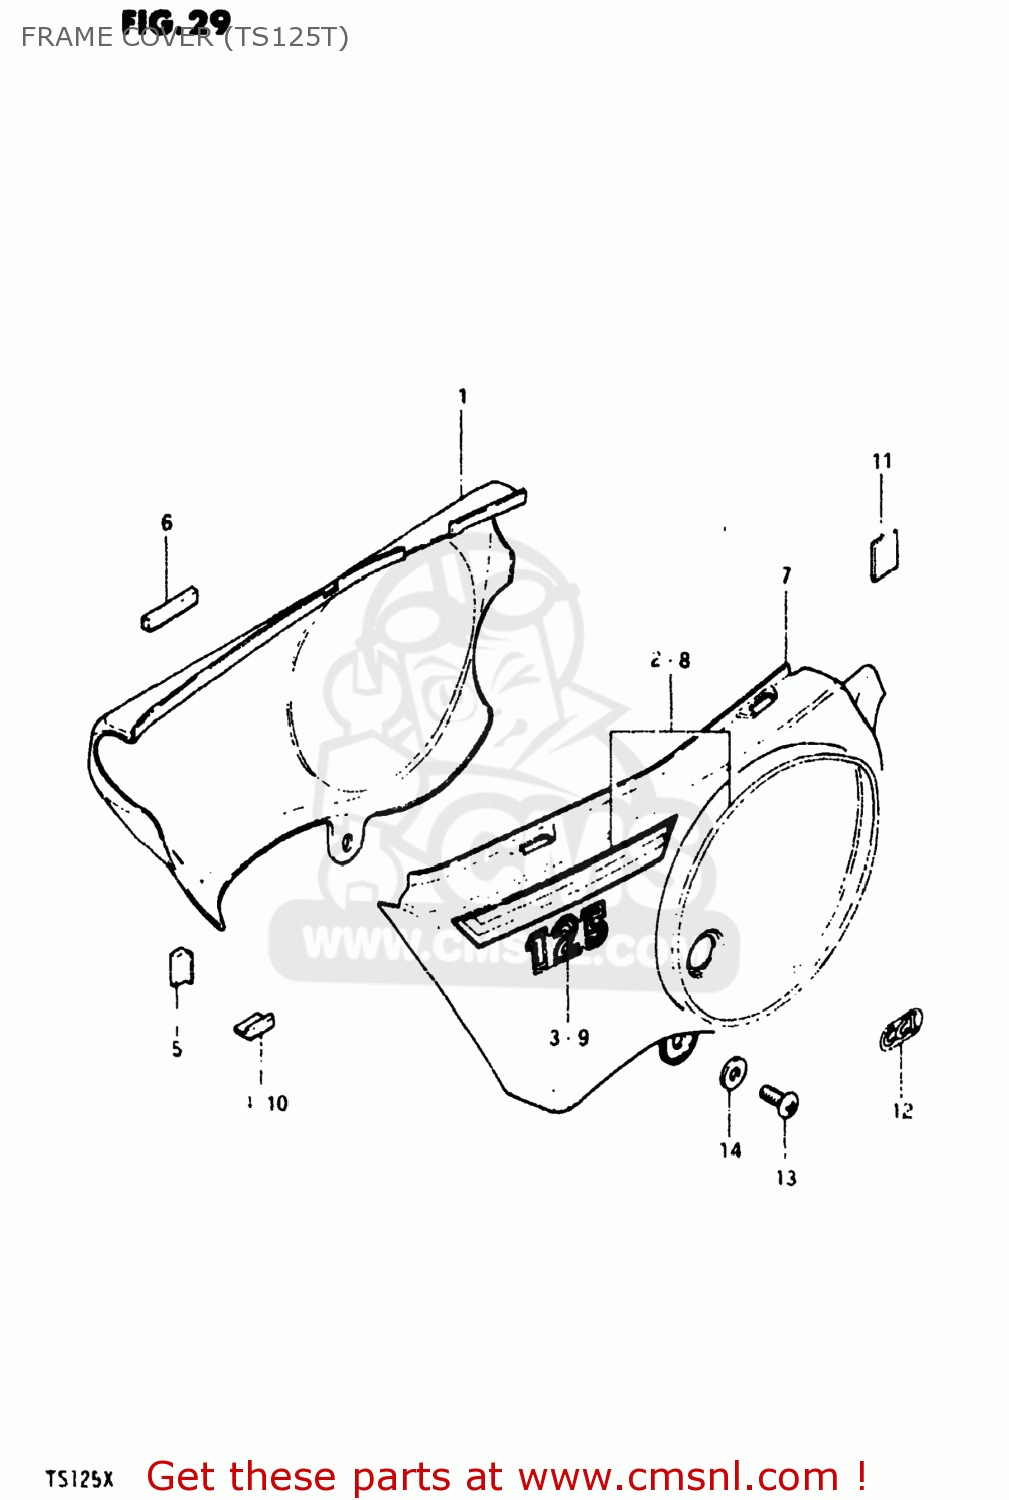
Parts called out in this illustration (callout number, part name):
1	COVER,FRAME,RIGHT
2	TAPE SET,FRAME COVER
3	EMBLEM
4	CUSHION,FRAME COVER
5	CUSHION,FRAME COVER
6	CUSHION,FRAME COVER
7	COVER,FRAME,LEFT
8	TAPE SET,FRAME COVER
9	EMBLEM
10	CUSHION,FRAME COVER
11	PROTECTOR(170X95X3.0)
12	EMBLEM,CCIS
13	SCREW 6X12
14	WASHER
